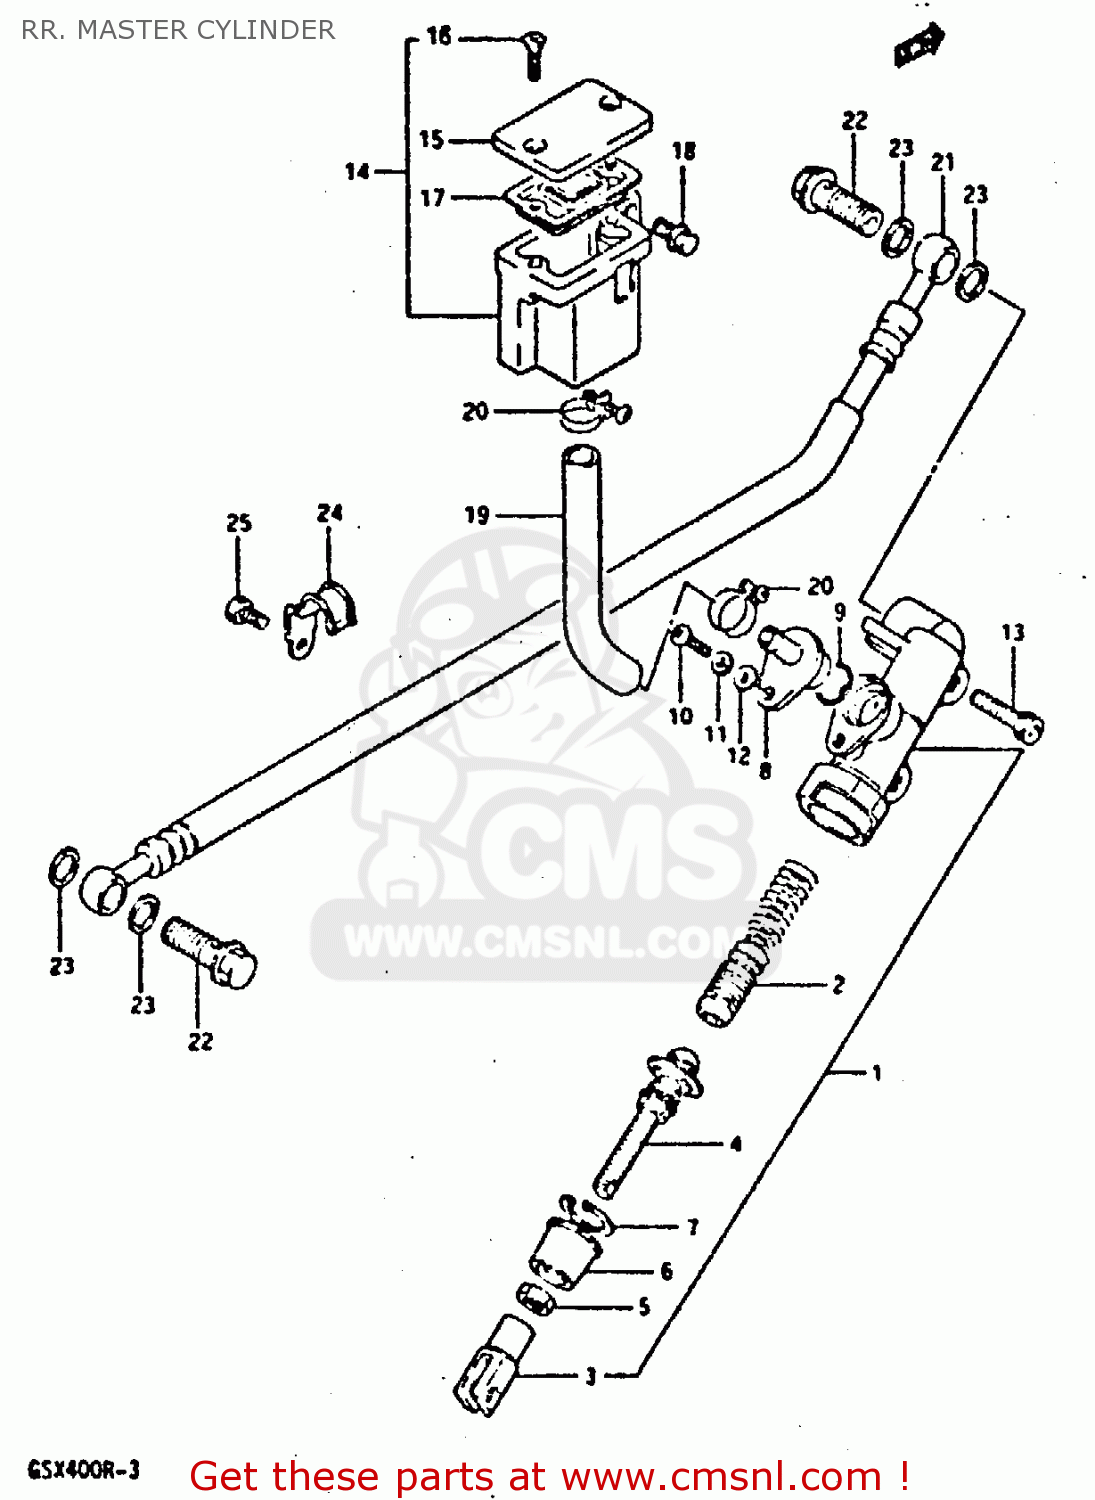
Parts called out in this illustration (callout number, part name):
1	CYLINDER ASSY,RR MASTER
3	YOKE
4	ROD,PUSH
5	NUT,MASTER CYLINDER
6	BOOT
7	CIRCLIP
8	CONNECTOR
9	O RING
10	SCREW
11	LOCK WASHER
12	WASHER
13	BOLT, 6X16
14	TANK ASSEMBLY,RESERVOIR
15	CAP
16	SCREW
17	DIAPHRAGM
18	BOLT
20	CLAMP
22	BOLT UNION
23	WASHER(10X15X1.5)
24	CLAMP,REAR BRAKE HOSE NO
25	BOLT
